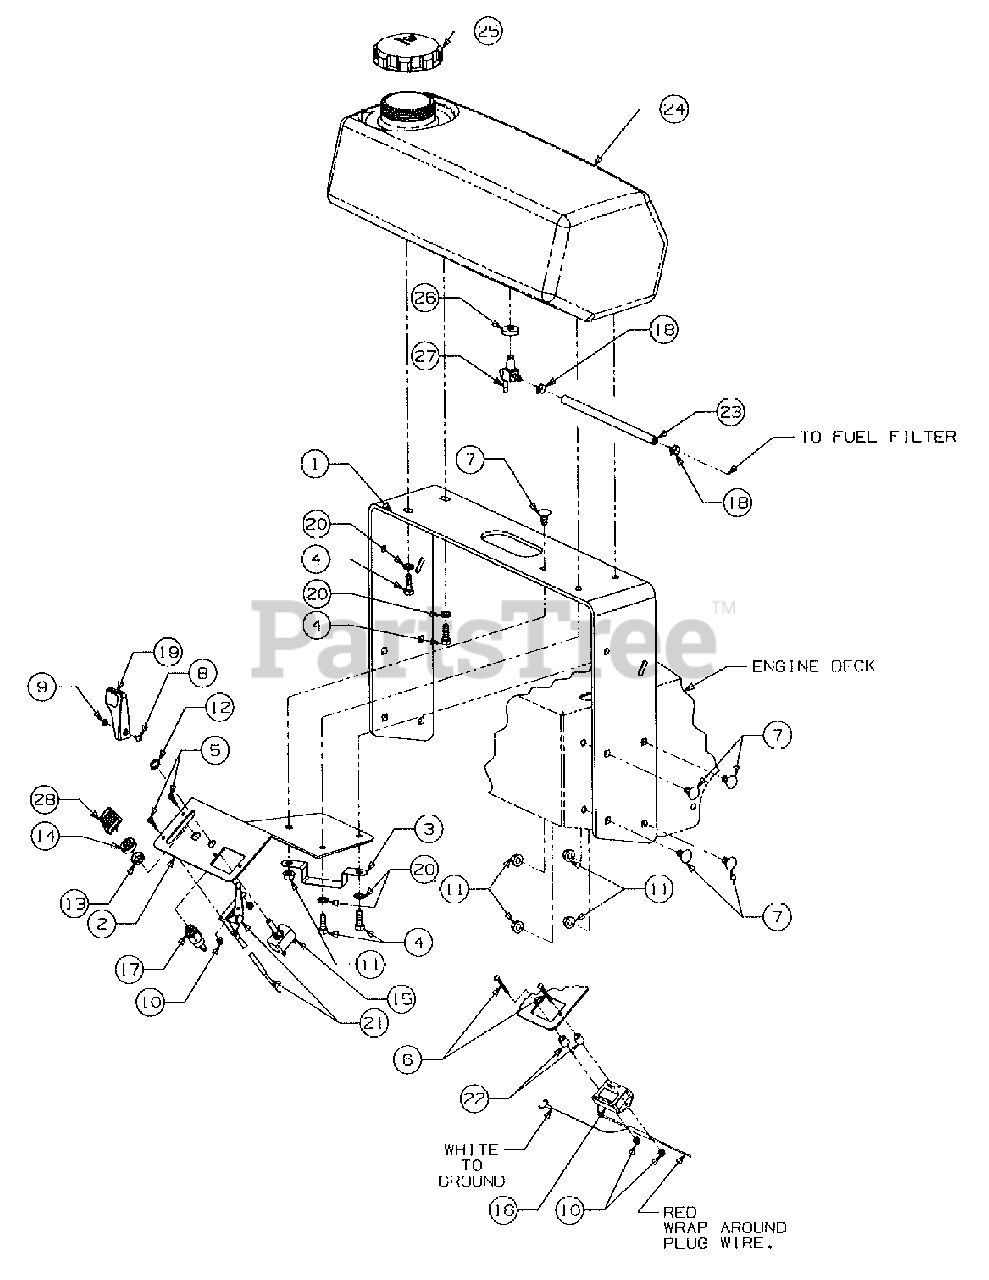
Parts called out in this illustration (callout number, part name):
1	Support, Lower Handle
2	Panel w/Graphic, Control
2	Graphic, Control Panel
3	Bracket, Cable Retainer
4	Screw, Hex Cap, 3/8-16 x 1.0 Gr 5
5	Screw, Pan Hd Cutting, #10-24 x .75
6	Bolt, Pan Head, #10-24 x 1.50
7	Bolt, Sht Nk Carriage, 3/8-16 x .75 Gr 5
8	Screw, Cross Rec Truss Hd, #8-32 x .38
9	Nut, Hex, #8-32
10	Nut, Hex Nylock, #10-24
11	Nut, Hex Flanged Lock, 3/8-16
12	Nut, Hex 1/2-27 x .100 Thk
13	Nut, Ignition Switch 5/8-32
14	Cap, Ignition Switch
15	Swtich, PTO
16	Meter, Hour/Tach
17	Switch, Ignition
18	Clamp, Hose
19	Knob, Throttle Control
20	Washer, Lock 3/8
21	Control, Throttle
22	Spacer, .315 ID x .50 OD x .52
23	Line, Fuel
24	Tank, Fuel
25	Cap, Fuel
26	Grommet, Shutoff Valve
27	Valve, Fuel Shutoff
28	Key, Ignition
